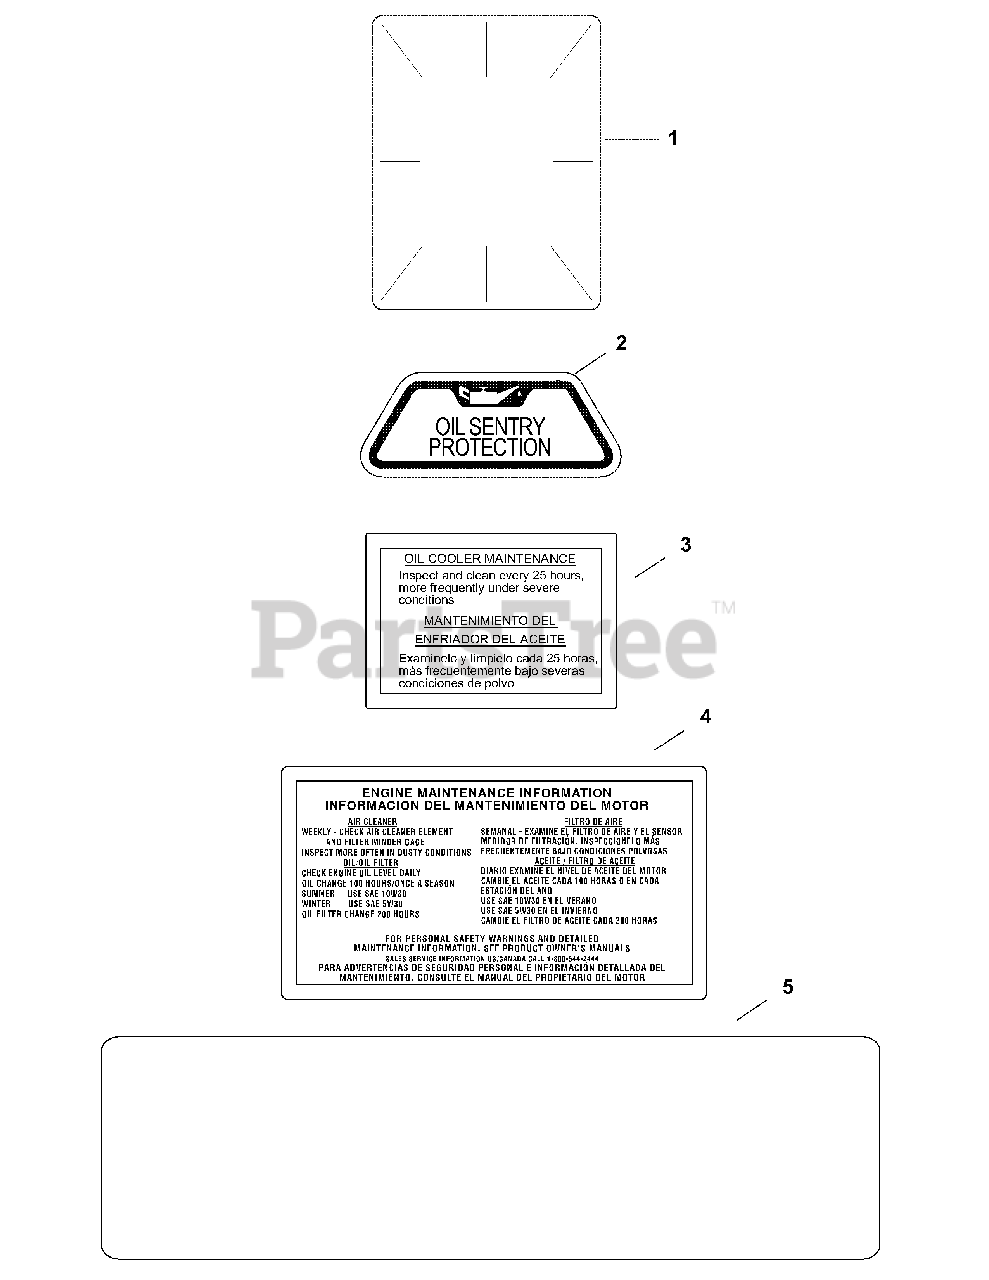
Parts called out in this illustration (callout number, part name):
1	Decal, Clear Laminate
2	Decal, Oil Sentry
3	Decal, Oil Cooler Maintenance
4	Decal, Engne Maintenance
